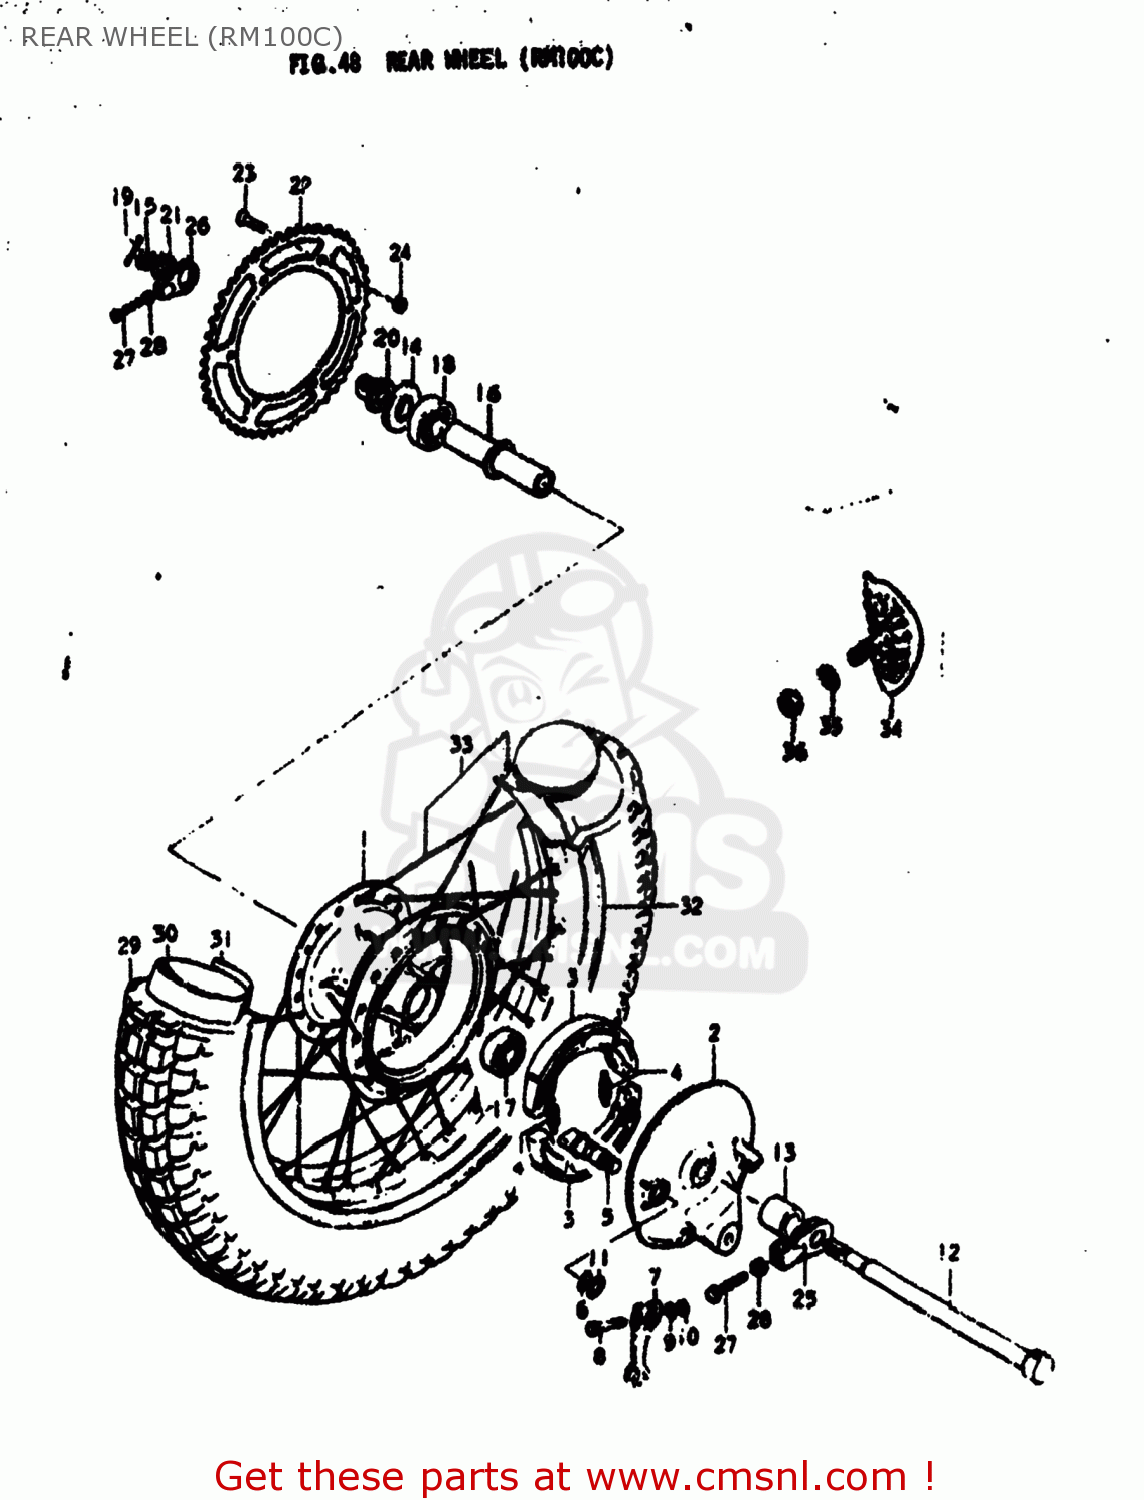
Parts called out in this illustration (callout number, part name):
1	HUB COMP,REAR
2	PANEL,REAR HUB
3	SHOE,BRAKE
4	SPRING(L:34)
5	CAM,FR BRAKE
6	O RING(D:2.5,ID:11.4)
7	LEVER,REAR BRAKE CAM
8	BOLT
9	WASHER
10	NUT
11	WASHER(12.5X20X1)
12	AXLE,REAR
13	SPACER(15.2X22X26)
14	SPACER,RR AXLE,L
15	NUT, REAR AXLE
16	SPACER,RR WHEEL HUB BEARING
17	BEARING
18	BEARING
19	COTTER PIN
20	SPACER,CHAIN ADJUSTER,L
21	NUT
22	SPROCKET,REAR
23	SCREW
24	NUT
25	ADJUSTER,CHAIN,R
26	ADJUSTER,CHAIN,L
27	BOLT(8X40)
28	NUT
29	TIRE
30	TUBE ASSEMBLY,WHEEL,INNER
31	PROTECTOR,WHEEL,INNER
32	RIM,REAR WHEEL
33	SPOKE SET,REAR
34	STOPPER,BEAD
35	WASHER
36	NUT ,8MM
